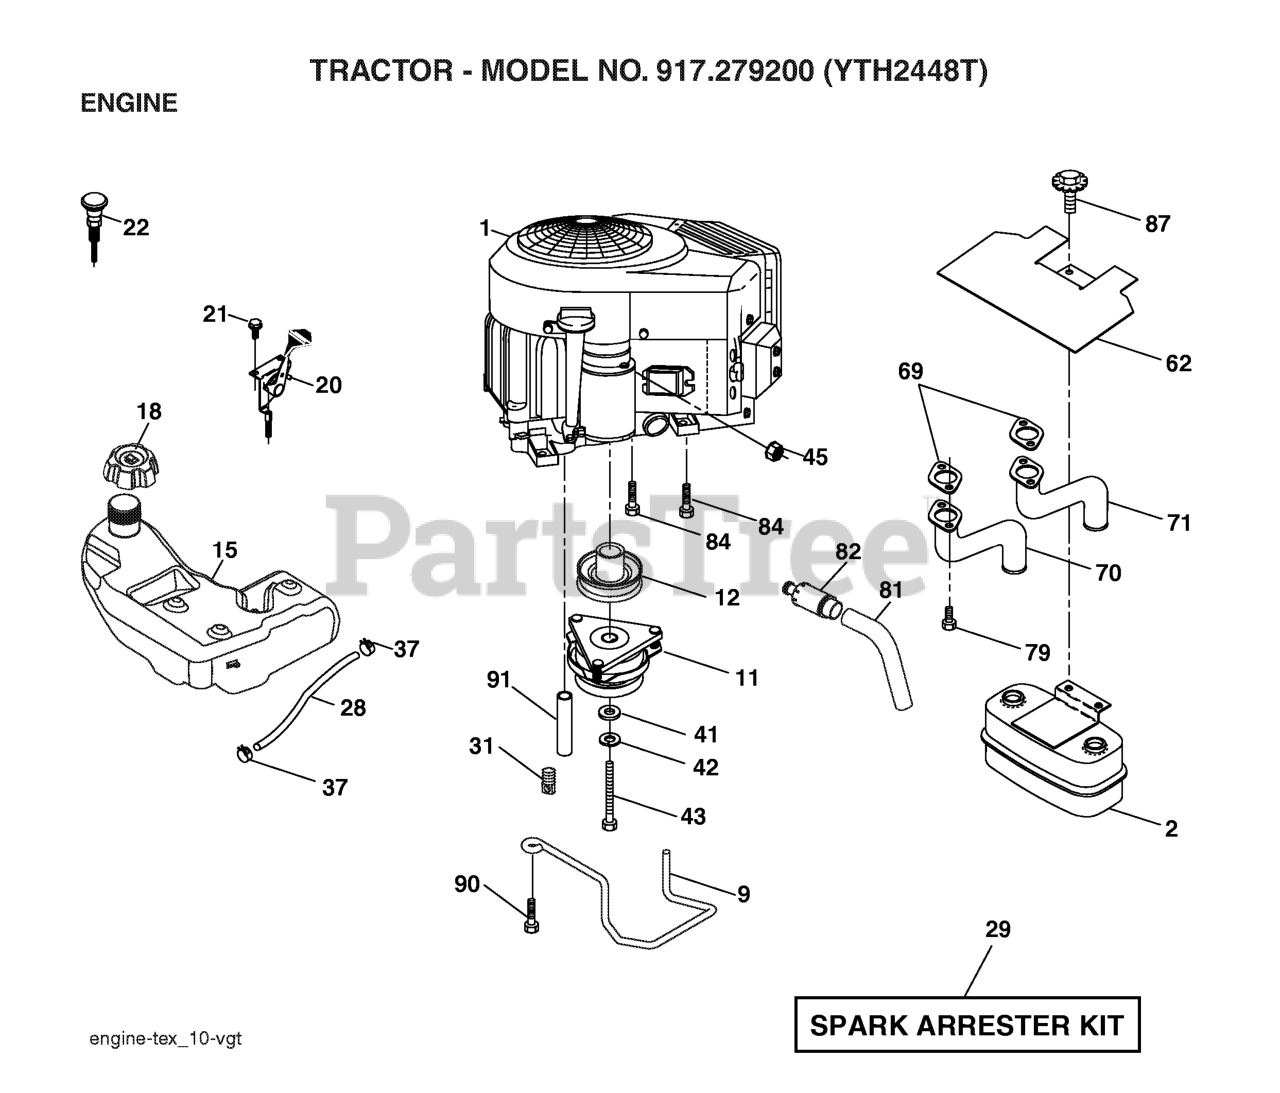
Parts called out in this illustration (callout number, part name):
2	MUFFLER.TWIN.CYL.LOW.TONE
9	KEEPER.BELT.ENGINE.3.25 (3 2)
11	CLUTCH ELECTRIC
12	PULLEY.ENGINE.ENX
15	TANK.FUEL.4GAL
18	CAP.FUEL.TANK.3"GREY
20	THROTTLE CABLE
21	SCREW
22	CONTROL.CHOKE.ERGO.PUSH-IN.BLA
28	LINE.FUEL.64"REAR.EMIS
29	KIT.SPARK ARRESTOR 794945 B&S
37	HOSE CLAMP
42	LOCKWASHER
43	BOLT HEX
45	NUT
62	RP SHIELD HEAT MUFFLER
69	GASKET.MUFFLER
70	RP.EXHAUST.TUBE.LH.BS/TWIN
71	EXHAUST.TUBE.RH.BS/TWIN
79	SCREW.SOCKET.HEAD.5/16-18
81	TUBE, DRAIN OIL ASM.
82	PLUG DRAIN OIL EASY
84	SCREW 3/8-16 X 1-1/2
87	BOLT.5/16-18UNCX1.W/SEMS.BLK
90	SCREW 3/8-16X1
91	BUSHING.1.375OD
